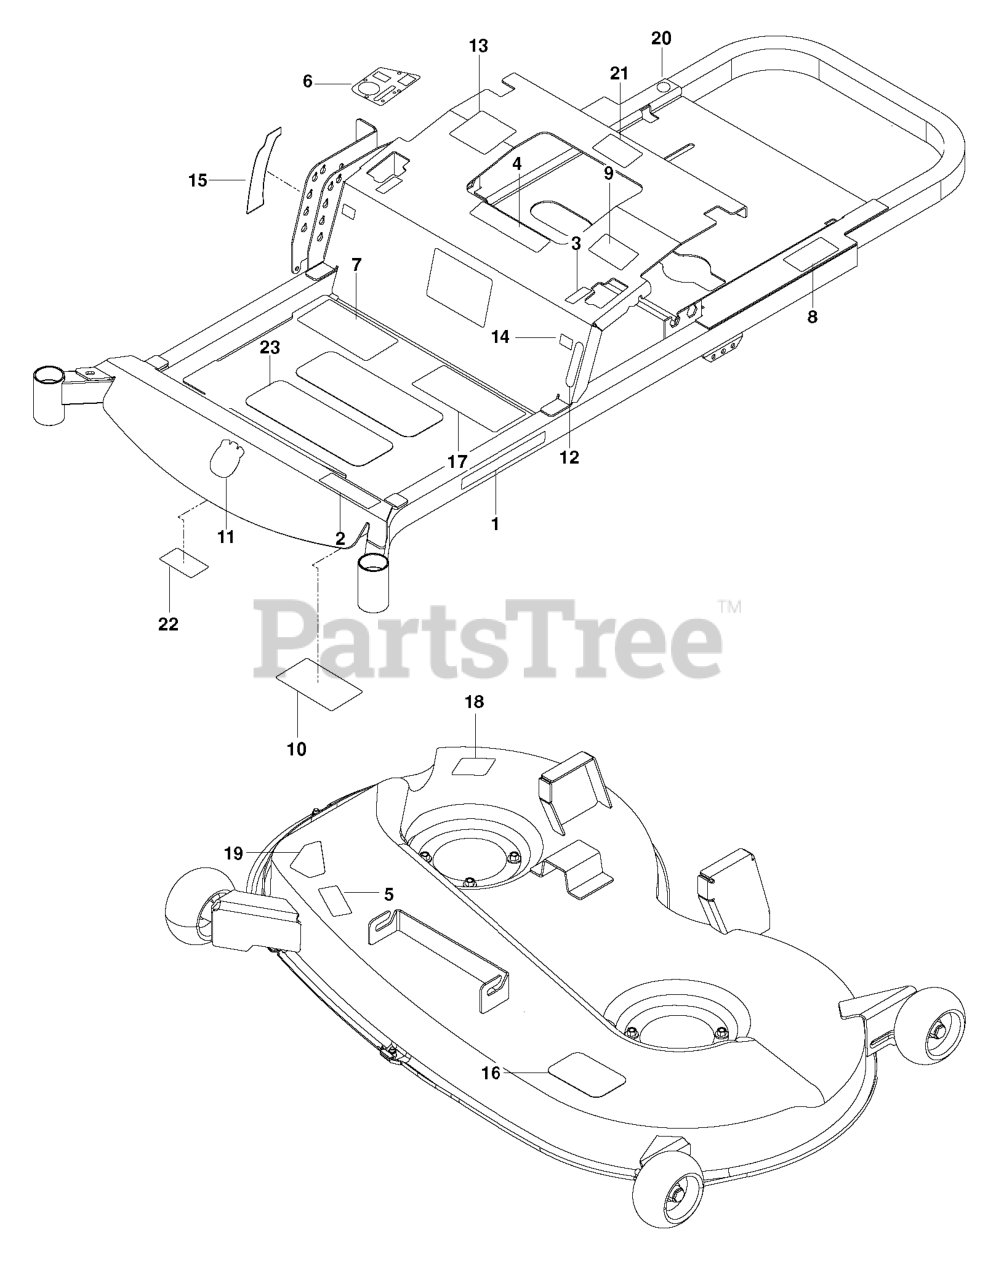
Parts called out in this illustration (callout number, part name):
1	RP.DECAL.BADGE.170MM.TEXTLOGO
3	DECAL, MOTION CONTROL
4	EURO DECAL-BATTERY WARNIN6
5	DECAL, EURO SEVERING
6	DECAL.ZTR.CONTROL.PANEL.HUSQV
7	DECAL.ZTR.STRTNGINS.SMARTIGNIT
8	DECAL, DO NOT TOW
9	DECAL, EXITING MOWER
10	DECAL, SERVICE
11	DECAL.AUGER.HUSQ.CROWN.SNOW
12	DECAL, PARK BRAKE
13	DECAL, CUSTOMER RESPNSIBILITY
14	DECAL, F.S.T.
15	DECAL, DECK HEIGHT, HUSQ
16	DECAL, BELT ROUTING
17	DECAL.ZTR.WARNING.SMARTIGNITIN
18	DECAL.DECK.6MIL./DEF.SHLD.WARN
19	DECAL, CPSC
20	DECAL.E85.WARNING.2012
21	DECAL.FENDER
23	ANTI-SKID PAD
